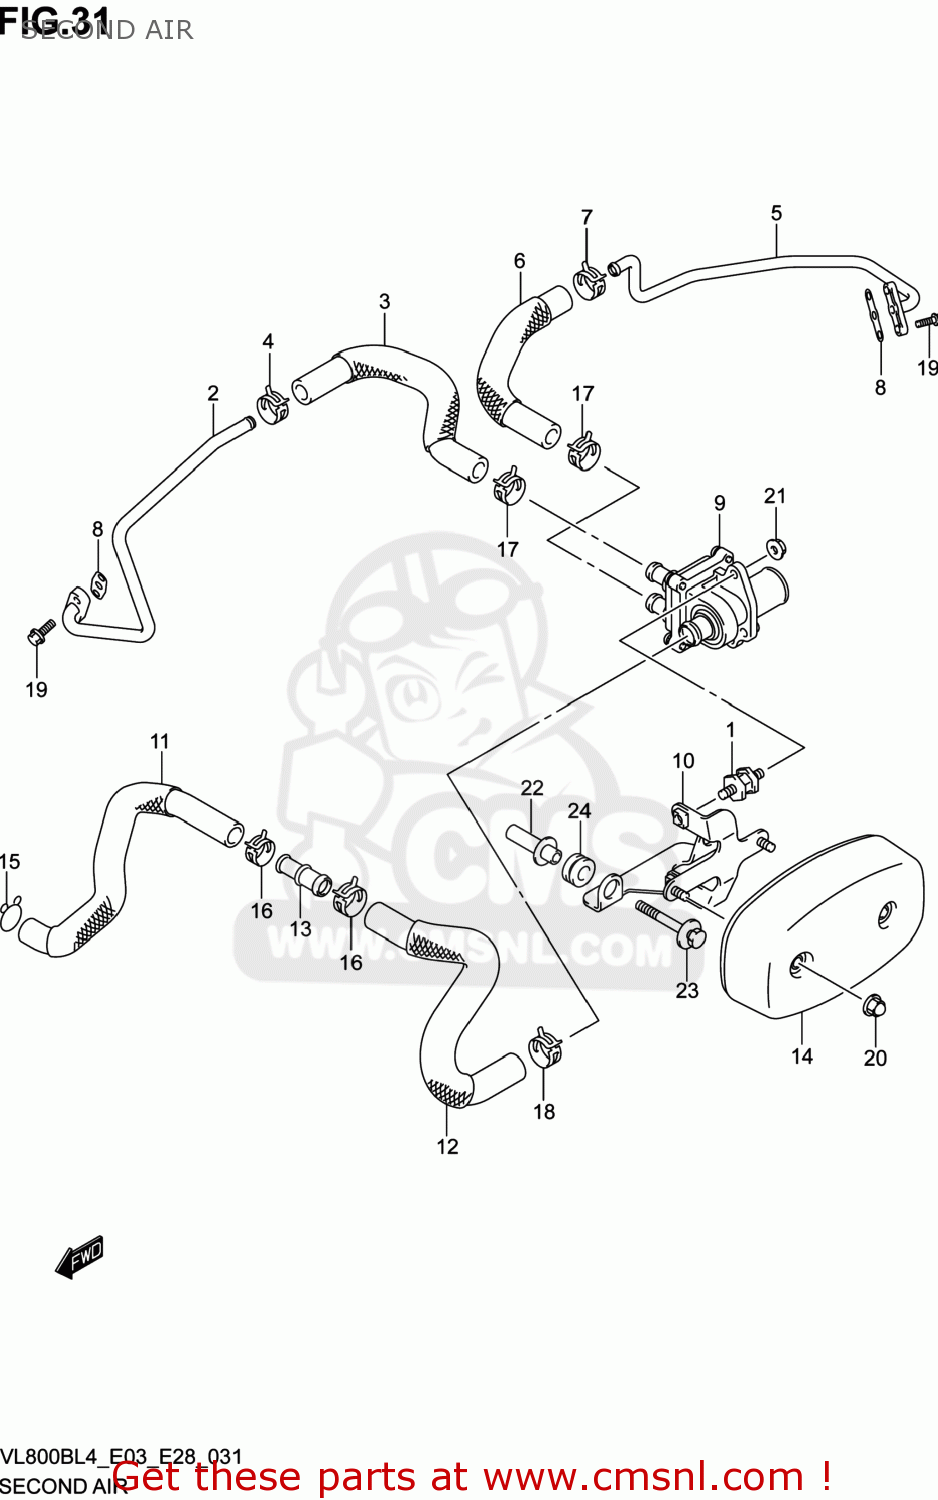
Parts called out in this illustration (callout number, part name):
1	BOLT,CUSHION
2	PIPE,2ND AIR FR
3	HOSE,2ND AIR VALVE FR
4	CLIP
5	PIPE,2ND AIR RR
6	HOSE,2ND AIR VALVE RR
7	CLIP
8	GASKET,2ND AIR PIPE (NAS)
9	VALVE ASSY,2ND AIR
10	BRACKET,2ND AIR SPRT
11	HOSE,2ND AIR CLEANER
12	HOSE,2ND AIR CLEANER
13	JOINT,2ND AIR CLEANER HOSE
14	COVER,2ND AIR VALVE
15	CLIP
16	CLIP
17	CLIP
18	CLIP
19	BOLT
20	NUT
21	NUT
22	SPACER,2ND AIR SPRT BRKT
23	BOLT(6X55)
24	CUSHION
